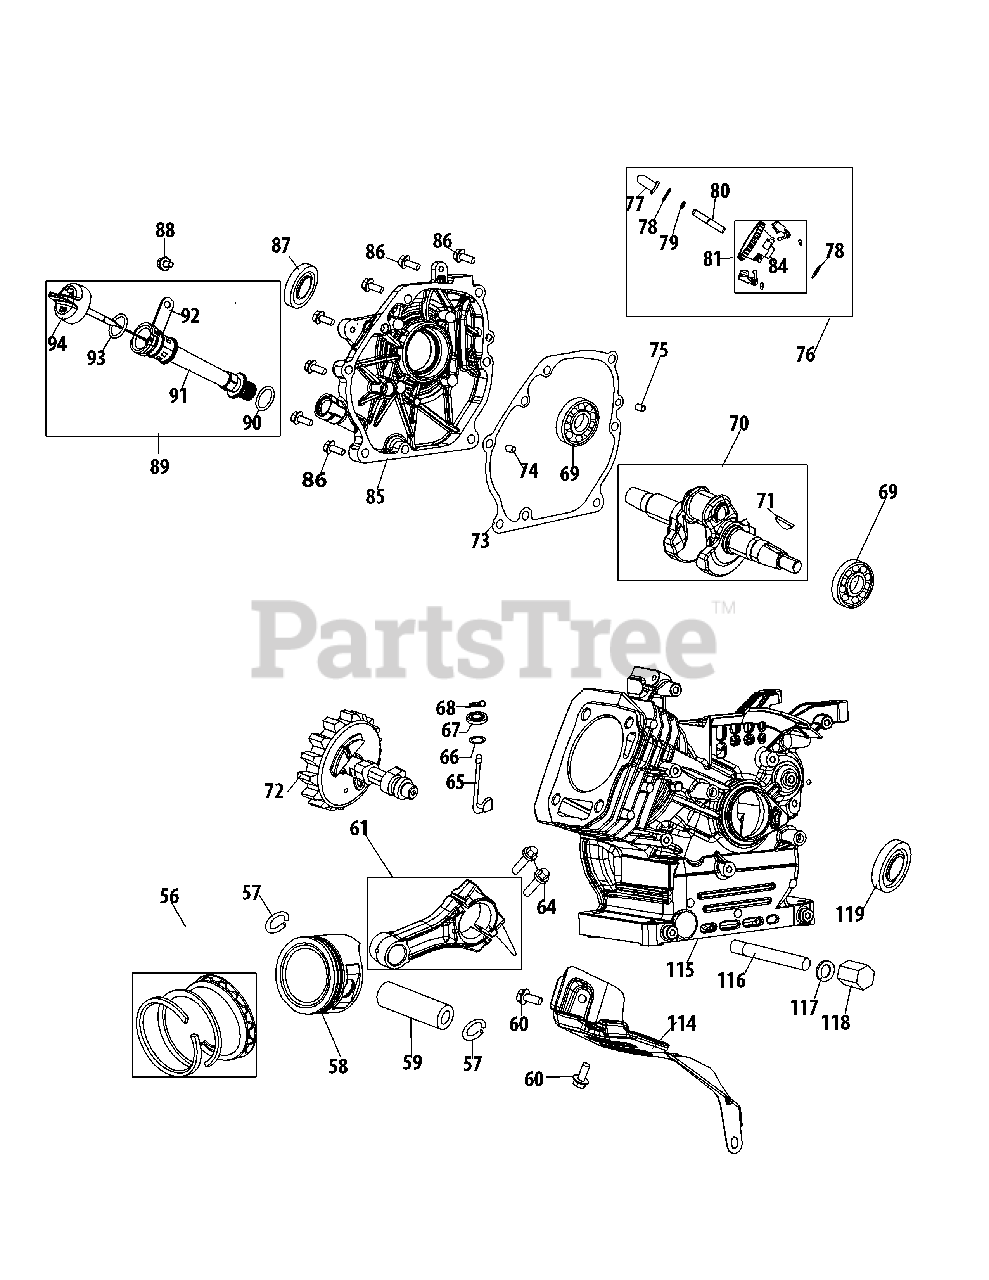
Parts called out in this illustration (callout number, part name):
56	Piston Ring Set
60	Bolt M6×12
61	Connecting Rod
64	Connecting Rod Bolt
65	Shaft,Governor Arm
66	O-Ring 5.2×1.9
67	Oil Seal 6×11×4
68	Cotter Pin
69	Bearing 6205
70	Crankshaft
71	Woodruff Key
73	Gasket, Crankcase Cover
74	Dowel Pin 9×14
75	Dowel Pin 7×14
76	Governor Gear
77	Governor Cup
78	Washer 6.2×0.6×15
79	Retaining Rings, Governor Shaft
80	Governor Shaft
81	Governor B0Dy
84	Governor Gear
85	Crankcase Cover
86	Bolt M8×32
87	Oil Seal 25×41.25×6
88	Bolt M6×16
89	Dipstick Assembly
90	O-Ring 15.5×1.5
91	Dipstick Tube
92	Clamp
93	O-Ring 21×2.77
94	Dipstick
115	Crankcase
116	Oil Drain Pipe
117	Washer 10×1.5×16
118	Washer,Drain Bolt(M10×1.25×15)
119	Oil Seal 25×41.25×6
